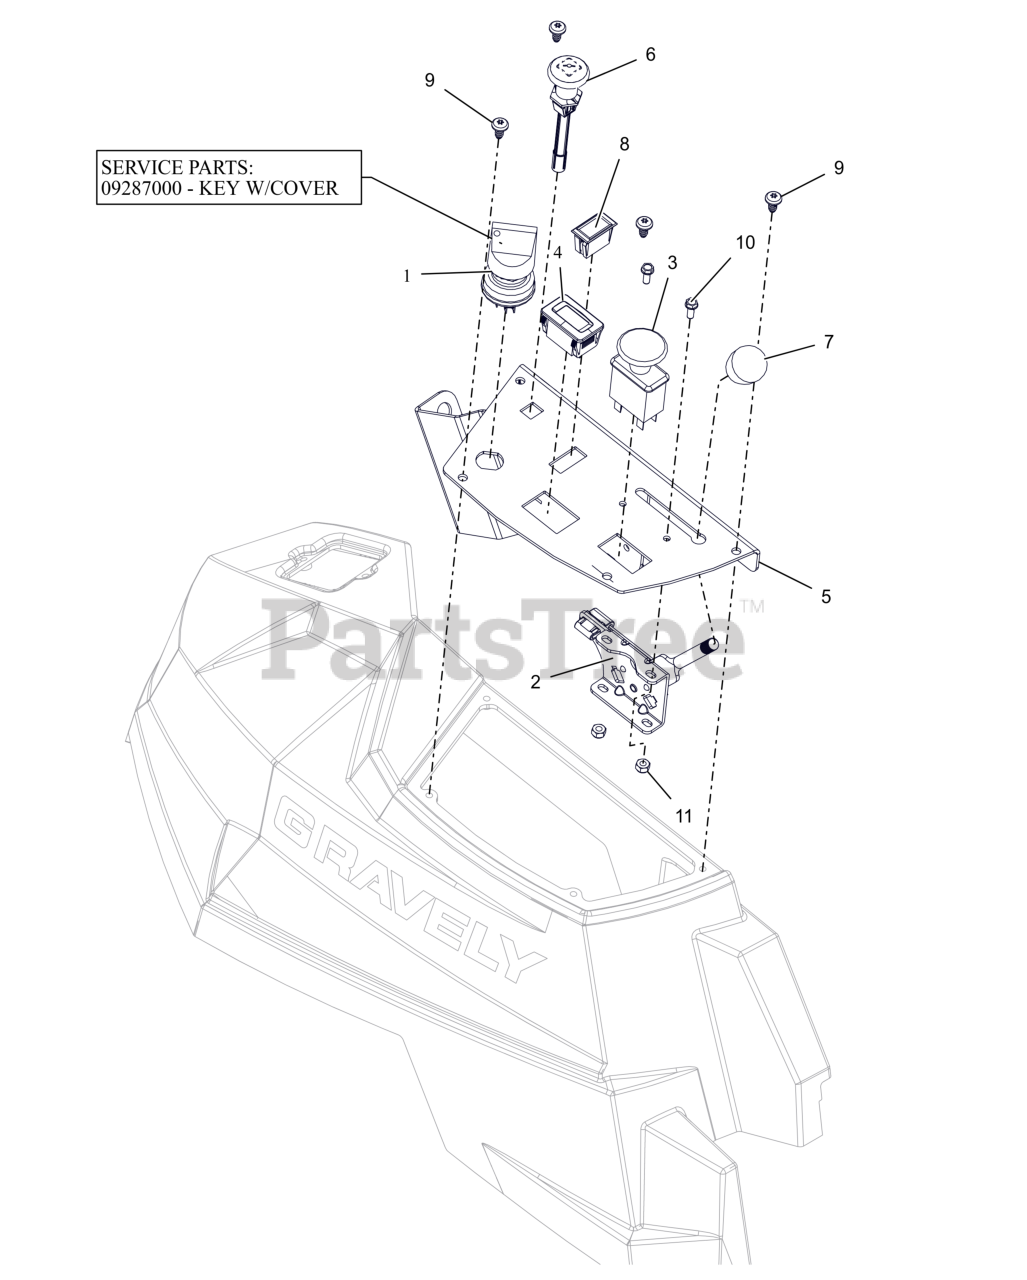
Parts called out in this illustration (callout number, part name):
1	SWITCH, IGNITION
1	KEY, W/ SHIELD
2	CABLE, PRO THROTTLE CONTROL
3	SWITCH, CLUTCH
4	HOUR METER
5	PANEL, HD CONTROL
6	CABLE - CHOKE, SNAP-IN
7	KNOB-CONTROL-BLACK .38-16X.50
8	SWITCH,BLANK
9	SCR-PAN .25-15X.50 6L H/LZB500
10	BLT, HWH #10-24X.50 ZCC
11	NUT-LK-NYL #10-24 G2 ZCC
